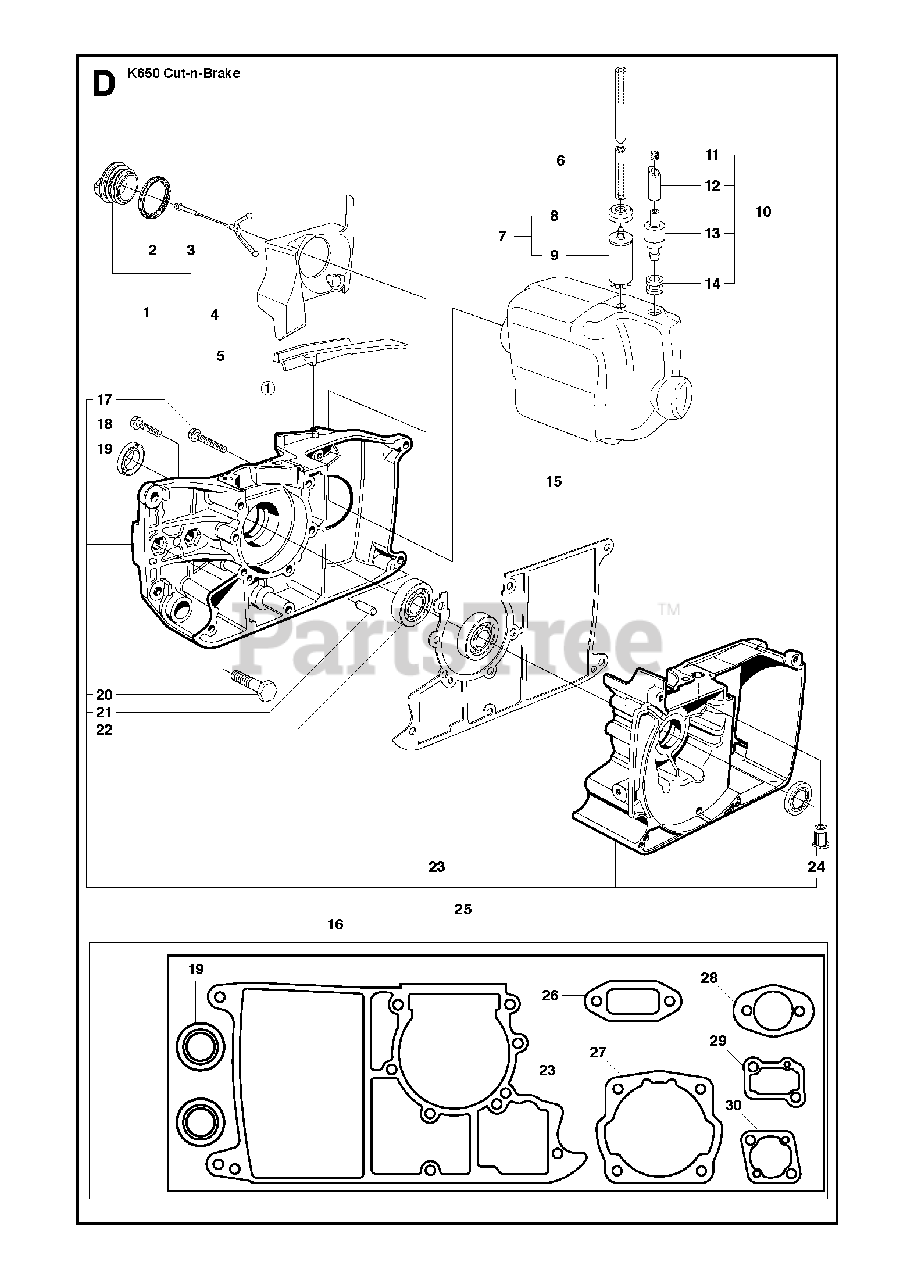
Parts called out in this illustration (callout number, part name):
1	TANK CAP ASSYIncl. 2, 3
7	FUEL FILTERIncl. 8, 9
10	TANK VENT ASSYIncl. 11 - 14
12	FUEL HOSE
16	CRANKCASE ASSYIncl. 17 - 24
19	SEALING RINGGasket kit 25
21	PARALLEL PIN
22	BALL BEARING
25	GASKET KITIncl. 19, 23, 26 - 30
